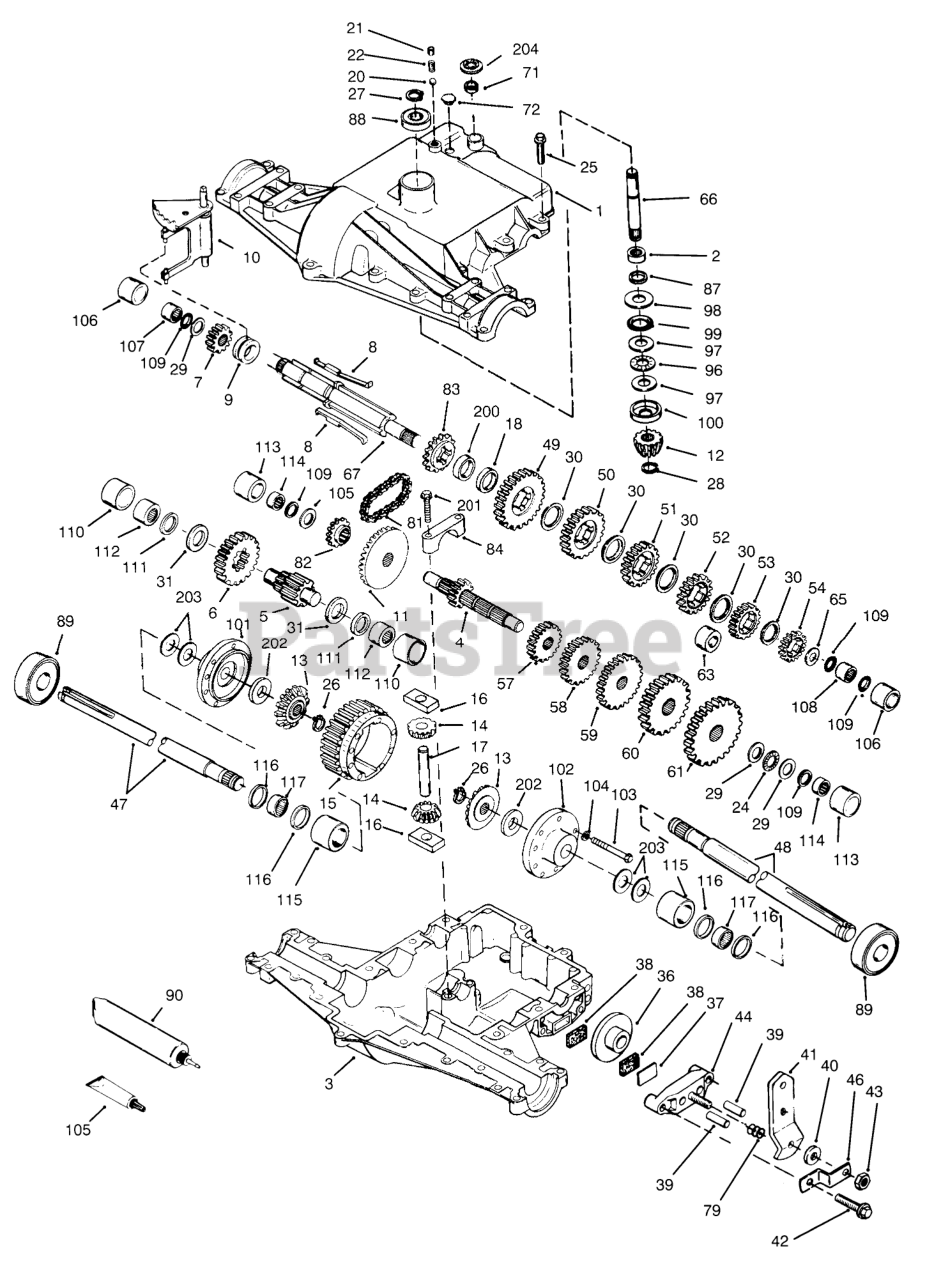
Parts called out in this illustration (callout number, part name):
1	Cover-Transaxle (Only On: 72042,72062)
2	Bearing-Needle (Only On: 72042,72062)
3	Case-Transaxle (Only On: 72042,72062)
4	Countershaft-Gear 9t (Only On: 72042,72062)
5	Shaft-Output (Only On: 72042,72062)
6	Gear-Output 35t (Only On: 72042,72062)
7	Gear-Spur 15t (Only On: 72042,72062)
8	Key-Shift (Only On: 72042,72062)
9	Collar-Shift (Only On: 72042,72062)
10	Fork-Shift (Only On: 72042,72062)
11	Gear-Bevel 33t (Only On: 72042,72062)
12	Pinion-Input Bevel 13t (Only On: 72042,72062)
13	Gear-Bevel 16t (Only On: 72042,72062)
14	Pinion-Bevel 10t (Only On: 72042,72062)
15	Gear-Ring (Only On: 72042,72062)
16	Block-Drive (Only On: 72042,72062)
17	Pin-Drive (Only On: 72042,72062)
18	Spacer .350-.340 Thick (Only On: 72042,72062)
20	Ball-Steel (Only On: 72042,72062)
21	Screw-Set 3/8-16x3/8 (Only On: 72042,72062)
22	Spring (Only On: 72042,72062)
24	Bearing-Thrust (Only On: 72042,72062)
25	Screw 5/16-18x1 1/4 (Only On: 72042,72062)
26	Ring-Retaining (Only On: 72042,72062)
27	Ring-Retaining (Only On: 72042,72062)
28	Ring-Retaining (Only On: 72042,72062)
29	Washer (Only On: 72042,72062)
30	Washer (Only On: 72042,72062)
31	Washer (Only On: 72042,72062)
36	Washer (Only On: 72042,72062)
37	Plate-Brake Pad (Only On: 72042,72062)
38	Pad-Brake 2/Pkg (Only On: 72042,72062)
39	Pin-Dowel (Only On: 72042,72062)
40	Washer (Only On: 72042,72062)
41	Lever-Brake (Only On: 72042,72062)
42	Screw 1/4-20x1 1/4 (Only On: 72042,72062)
43	Nut-Lock 5/16x24 (Only On: 72042,72062)
44	Holder-Brake Pad (Only On: 72042,72062)
46	Bracket-Brake Lever (Only On: 72042,72062)
47	Axle 12 9/16" Long (Only On: 72042,72062)
48	Axle 16 7/16" Long (Only On: 72042,72062)
49	Gear-Spur 41t (Only On: 72042,72062)
50	Gear-Spur 35t (Only On: 72042,72062)
51	Gear-Spur 30t (Only On: 72042,72062)
52	Gear Spur 25t (Only On: 72042,72062)
53	Gear Spur 22t (Only On: 72042,72062)
54	Gear Spur 19t (Only On: 72042,72062)
57	Gear Spur 15t (Only On: 72042,72062)
58	Gear Spur 20t (Only On: 72042,72062)
59	Gear Spur 25t (Only On: 72042,72062)
60	Gear Spur 28t (Only On: 72042,72062)
61	Gear Spur 30t (Only On: 72042,72062)
65	Washer (Only On: 72042,72062)
66	Shaft-Input 30.910" Lg (Only On: 72042,72062)
67	Shaft-Shifter/Brake (Only On: 72042,72062)
71	Ring-Square Cut (Only On: 72042,72062)
72	Plug-Threaded 9/16-18 (Only On: 72042,72062)
79	Spring (Only On: 72042,72062)
81	Chain-Roller #41 22" Lg (Only On: 72042,72062)
82	Sprocket 10t (Only On: 72042,72062)
83	Sprocket-Reverse 14t (Only On: 72042,72062)
84	Cap-Bearing (Only On: 72042,72062)
87	Seal-Oil 3/4" (Only On: 72042,72062)
88	Bearing-Ball (Only On: 72042,72062)
89	Bearing-Ball (Only On: 72042,72062)
90	Grease 32 Oz Bentonite (Only On: 72042,72062)
96	Bearing-Thrust (Only On: 72042,72062)
97	Washer (Only On: 72042,72062)
98	Washer (Only On: 72042,72062)
99	O Ring (Only On: 72042,72062)
100	Washer-Cupped (Only On: 72042,72062)
101	Carrier-Differential (Only On: 72042,72062)
102	Carrier-Differential (Only On: 72042,72062)
103	Screw 14-20x2 1/4 (Only On: 72042,72062)
104	Washer-Lock (Only On: 72042,72062)
105	Washer (Only On: 72042,72062)
106	Sleeve (Only On: 72042,72062)
107	Bearing-Needle (Only On: 72042,72062)
108	Bearing-Needle (Only On: 72042,72062)
109	O Ring (Only On: 72042,72062)
110	Sleeve (Only On: 72042,72062)
111	Ring-Square Cut (Only On: 72042,72062)
112	Bearing-Needle (Only On: 72042,72062)
113	Sleeve (Only On: 72042,72062)
114	Bearing-Needle (Only On: 72042,72062)
115	Sleeve (Only On: 72042,72062)
116	Ring-Square Cut (Only On: 72042,72062)
117	Bearing-Needle (Only On: 72042,72062)
150	Gasket Loctite #515 (Only On: 72042,72062)
200	Spacer .276-.268 Thick (Only On: 72042,72062)
201	Screw 1/4-20x1 1/4 (Only On: 72042,72062)
202	Washer (Only On: 72042,72062)
203	Washer (Only On: 72042,72062)
204	Nut-Push (Only On: 72042,72062)
